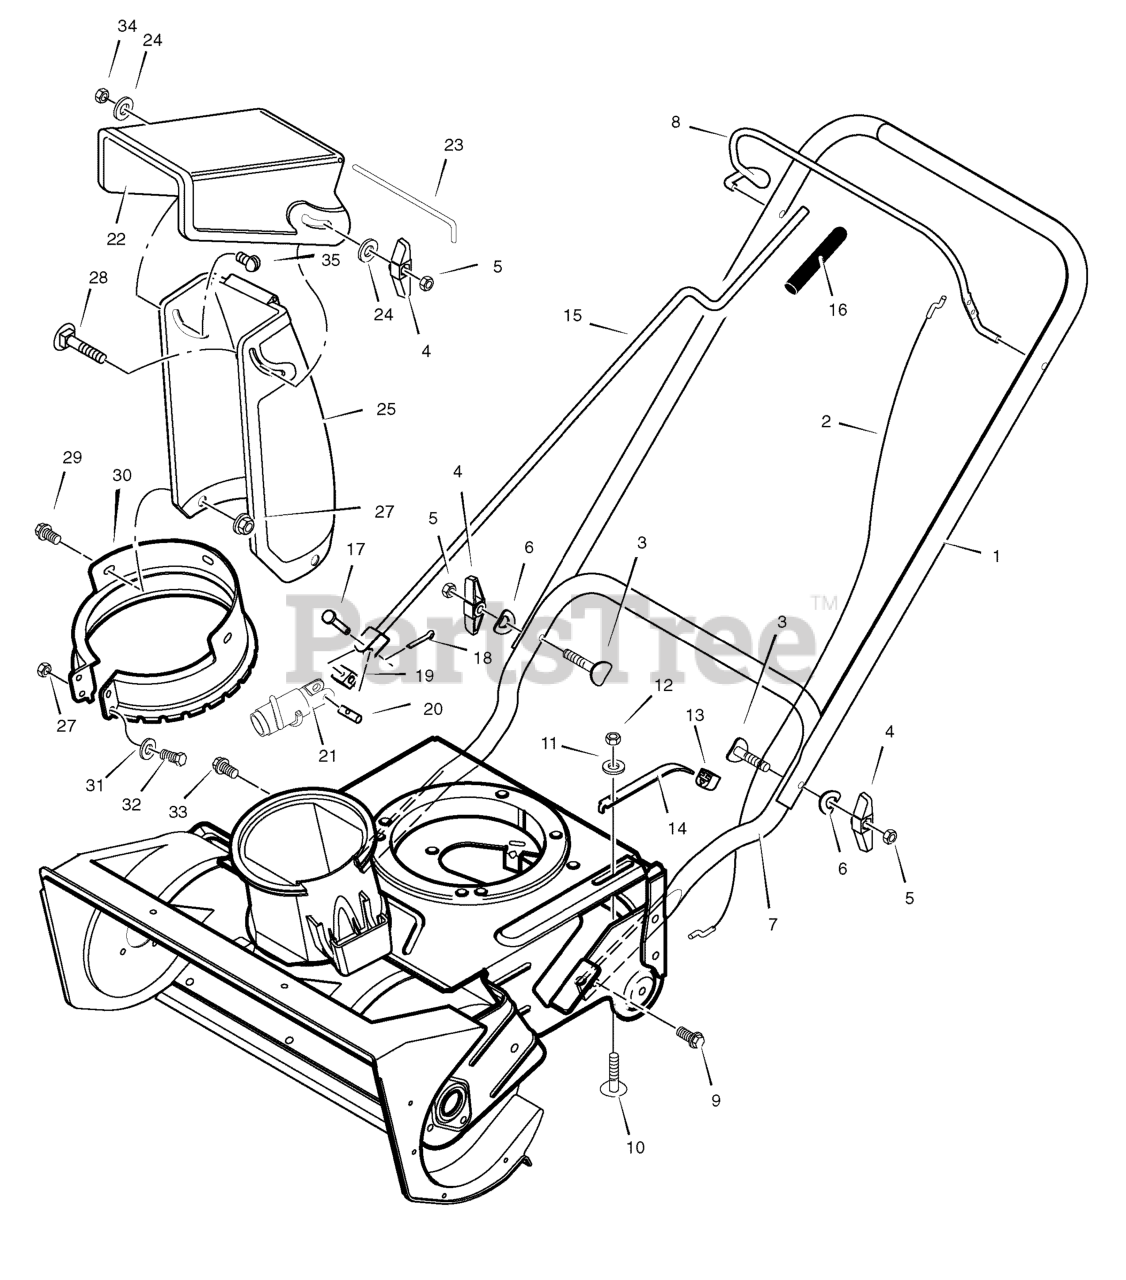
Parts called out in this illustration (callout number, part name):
1	Handle, Upper
2	Cable, Auger Drive
4	Knob
5	Nut
7	Handle, Lower
8	Lever, Auger Drive
9	Screw
13	Bushing, Tensioner
14	Bracket, Cable Tensioner
15	Rod, Crank
16	Grip, Crank Rod
17	Pin, Clevis
18	Pin, Cotter
19	Block, Universal Pivot
21	Gear, Worm
22	Deflector
23	Pin, Pivot
24	Washer
25	Chute, Discharge
30	Ring, Chute
31	Washer
33	Bolt
34	Locknut
